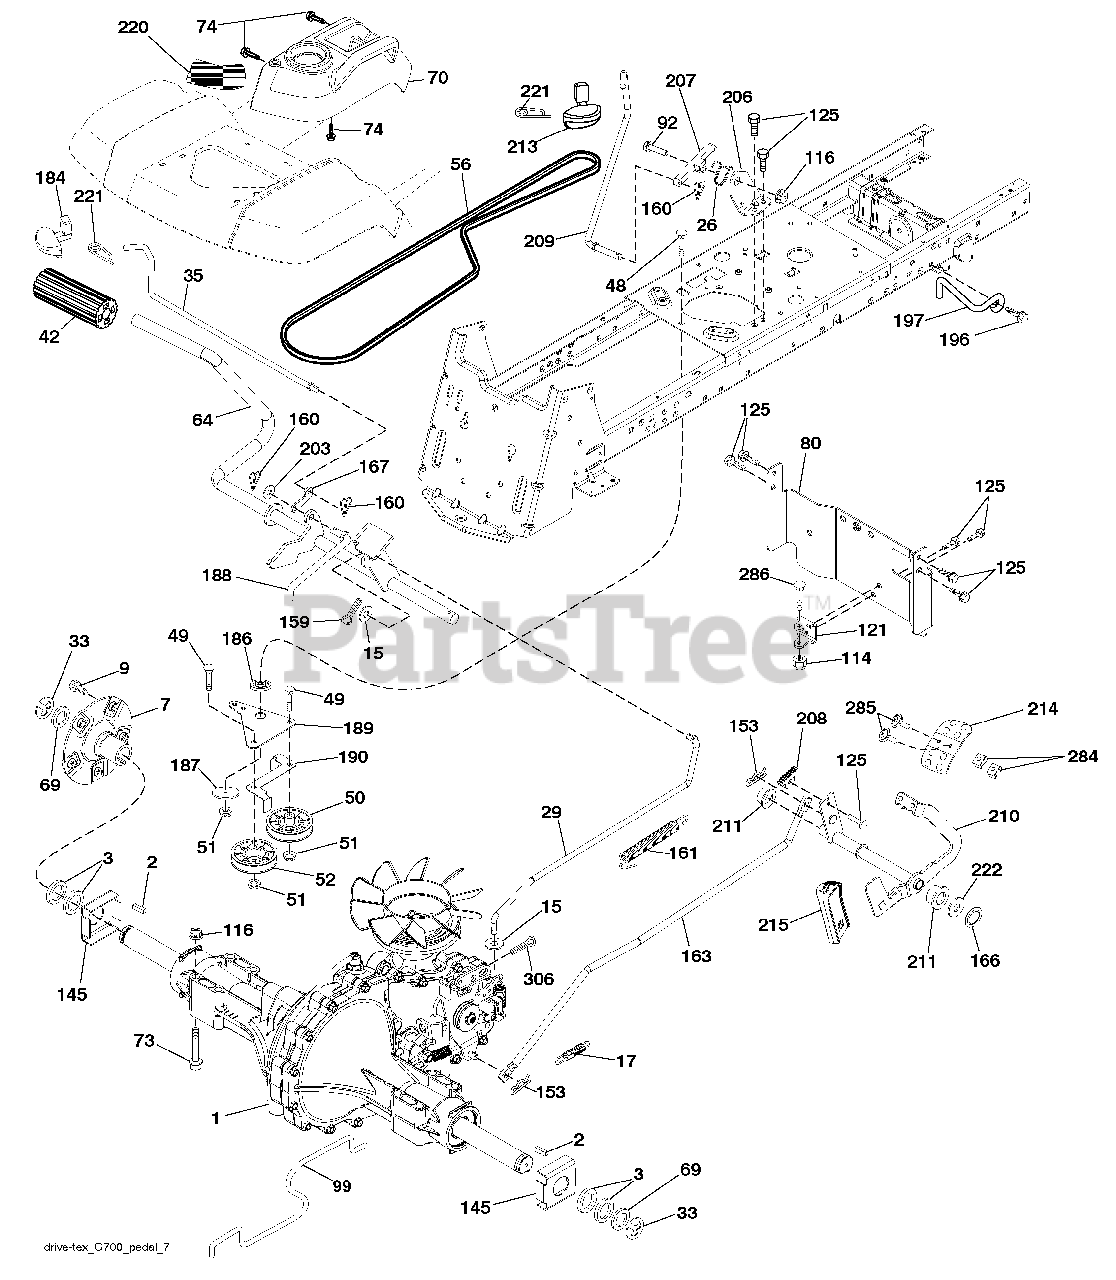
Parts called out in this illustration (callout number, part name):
2	Key 1/4 x 2.5
3	Washer Thrust Axle Hardened
7	Hub Asm. Wheel
9	Bolt Hub Wheel
15	Washer 13/32 x 13/16 x 16 Ga.
17	Spring, Brake
26	Spring Return Cruise
29	Rod, Brake
35	Rod, Brake, Park
42	Cover, Foot Pedal
48	Bolt Carr Sh 3/8-16 x 1-1/2 Gr.5
50	Pulley Idler Flat
51	Lock Nut 3/8-16
52	Idler V-Groove 910" Offset
56	V-Belt, Drive
64	Shaft Asm. Pedal Brake Control
69	Washer 1-1/32 x 1-5/8 x 16 Ga.
70	Console Asm
73	Bolt Hex 5/16-18 x 3 Gr. 5
74	Screw 1/4 x 1/2
80	Strap Torque
92	Bolt 5/16-18 x 1/2
99	Spring Bypass
114	Nut Lock Hex W/Ins. 5/16-18 unc
116	Nut Lock Hex Flange 5/16-18
121	Bracket Strap Torque
125	Screw 5/16-18 x 3/4
145	Washer Axle Flange
153	Retainer Spring
159	Pin Cotter 1/8 x 3/4
160	Retainer Clip
161	Spring, Return, Clutch
163	Rod Pedal Control
166	Nut Push .625
167	Latch Brake Parking
184	Handle Parking Brake
186	Spacer Retainer
187	Washer
188	Link Clutch Ground Drive
189	Bellcrank Ground Drive
190	Keeper Bellcrank Ground Drive
196	Screw 3/8-16 x 1
197	Bracket Clutch Anti-Rotation
203	Washer 11/32 x 11/16 x 16 Ga.
206	Bracket Mount Latch Cruise
207	Latch Control Cruise
208	Gear Sector Control Cruise
209	Rod Control Cruise
210	Rocker Asm. Pedal Control
211	Bearing Nylon
213	Knob Control Cruise
214	Pedal Forward
215	Pedal Reverse
220	Reflector RH
221	Retainer Spring Clip Handle
222	Washer 21/32 x 1-1/4 x 10 Ga.
284	Nut U-Chnl. 1/4-20
285	Screw PHD 1/4-20 Box Drive
286	Bolt 5/16-18 x 2.50
306	Pin Cotter 1/8 x 1
